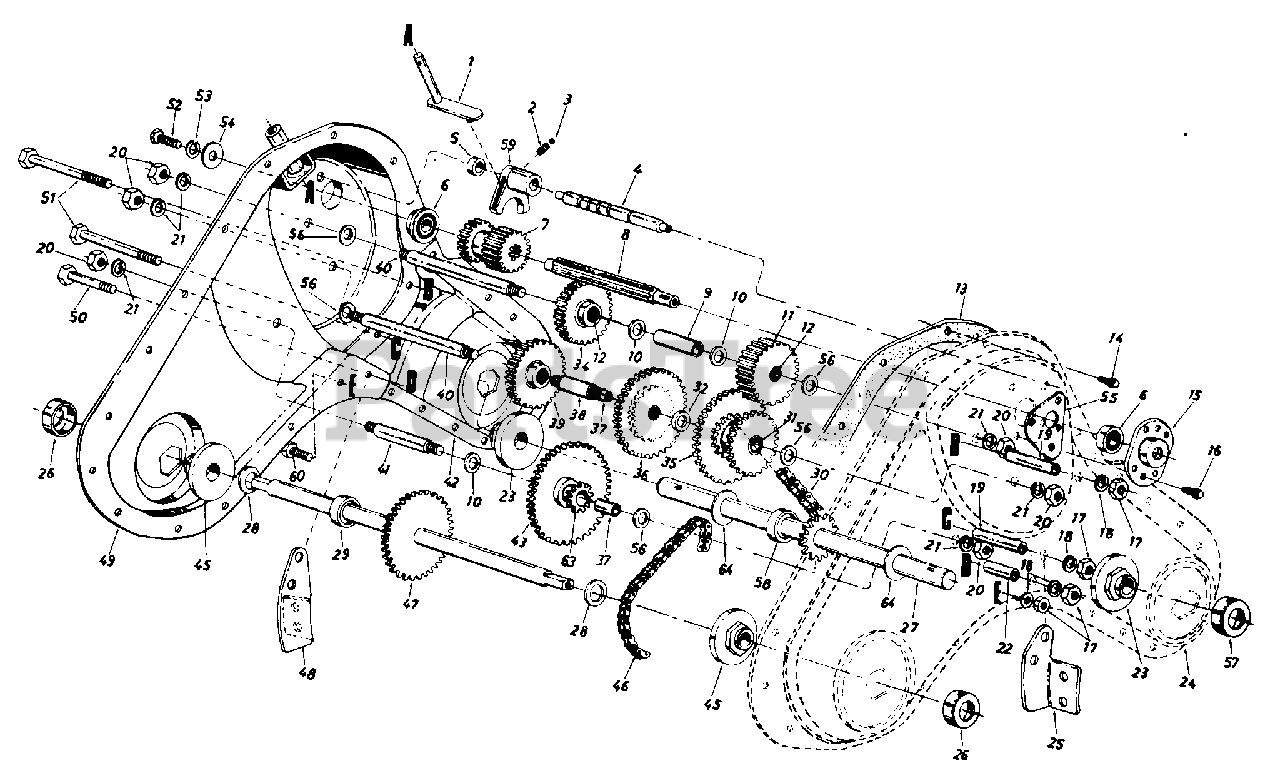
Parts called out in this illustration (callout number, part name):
1	BRACKET ASSY-SHIFT
2	SPRING-COMPRESSION
3	BALL-DETENT
4	SHAFT-DETENT
5	SPACER-.505 1D
6	BEARING-BALL
7	GEAR-SPUR-16T
8	SHAFT-INPUT
10	WASHER-FL-.640ID X 1.24OD X .06HDN
11	GEAR-SPUR-30T
12	BEARING-NEEDLE
13	GASKET
14	SCREW-HEX WASH SF TAPP
15	HOUSING-BRG
16	SCREW-HEX HD TAP 1/4-20 X 7.5
17	NUT-HEX 5/16-18
18	WASHER-LOCK-5/16
19	SPACER-1.560 1D
20	NUT-HEX 7/16-20
21	WASHER-FL
22	SPACER-1.015 1D
23	BEARING
24	HOUSING ASSY-LH
27	SHAFT ASSY-TINE
28	WASHER-FL
29	SPACER
30	#50 CHAIN 5/8 PITCH X 52L E
31	BEARING-NEEDLE
32	WASHER-FL
34	GEAR-SPUR-30T
35	GEAR-30/44T
36	GEAR-SPUR-44T
37	BEARING-SLEEVE .627 X .750 X .936
39	GEAR-SPUR-30T
40	JACKSHAFT
41	JACKSHAFT
46	#420 CHAIN-1/2 PITCH
47	SHAFT ASSY-WHEEL
51	SCREW-HEX
52	BOLT - 1/4-28 X 5/8 61.5
53	WASHER-LOCK-3/8
54	WASHER-FL
55	BRACKET-GEAR POS
56	WASHER-FL
57	COVER-DUST
58	SPACER
59	FORK-SHIFT
60	SCREW-HEX 5/16-18 X .75
63	SPROCKET ASSY-10T
64	WASHER-FL-1.03 ID X 1.62 X .03 HD
